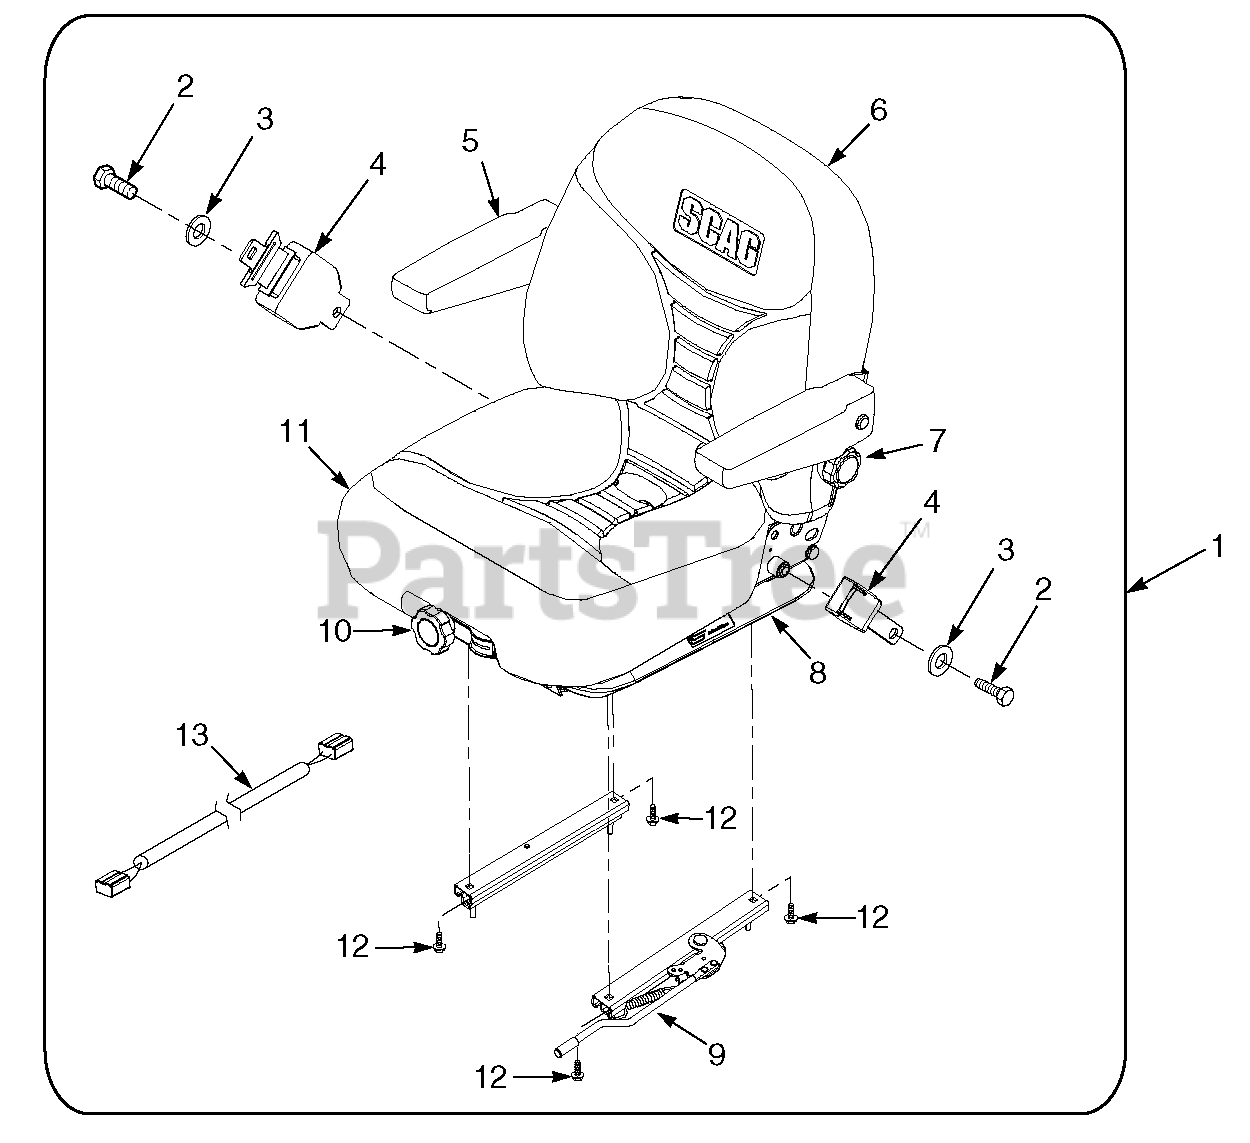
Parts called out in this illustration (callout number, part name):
1	Suspension Seat Assembly w/seat belt
2	Bolt, Hex Head 7/16-20 x 1"
3	Flatwasher, 7/16-.500 x 1.25 x .083
4	Retractable Seat Belt
5	Armrest Only
5	Armrest Assembly Kit, LH
5	Armrest Assembly Kit, RH
6	Back Cushion Kit
7	Lumbar Kit
8	Shock Absorber Kit
9	Seat Adjustment, Track Set
10	Weight Adjustment Kit
11	Seat Cushion Kit Seat Drain Kit
12	Bolt, Hex Head 5/16-18 x 1-3/4"
13	Wire Harness Adapter
